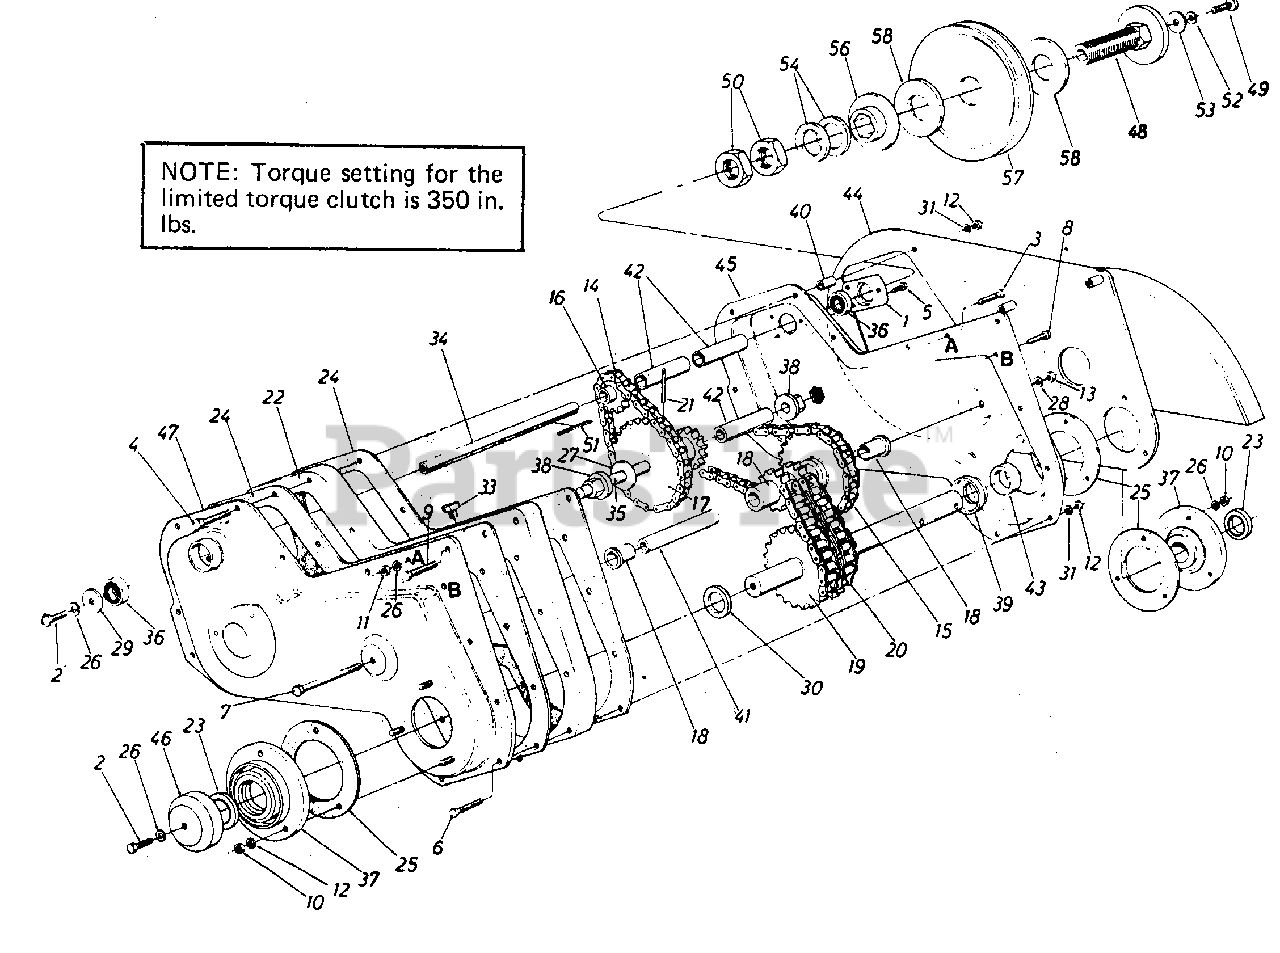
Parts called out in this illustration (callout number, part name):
1	Bearing Housing 1-3/8" Dia.
2	Hex Bolt 5/16-18 x .88" Lg. Spec.
3	Hex Bolt 5/16-18 x 1.50" Lg.*
4	Hex Bolt 1/4-20 x 2.75" Lg.*
5	Hex Wash. S-Tap. Scr. 1/4-20 x 50" Lg.
6	Hex Bolt 1/4-20 x 1.50" Lg.*
7	Hex Bolt 3/8-16 x 4.5" Lg.
8	Hex Wash. Hd. Bolt 1/4-20 x 1.5" Lg.
9	Hex Wash. TT Tap Scr. 5/16 18 x 1.75" Lg.
10	Hex Cent. L. Nut 5/16-18 Thd.
11	Hex Nut 5/16-18 Thd.*
12	Hex Nut 1/4-20 Thd.*
13	Hex Nut 3/8-16 Thd.*
14	#41 Chain 1/2" Pitch x 34 Links Endless
15	#42 Chain 1/2" Pitch x 48 Links-Endless
16	Sprocket 10Tooth.500" Pitch
17	10 & 28 Teeth Sprocket Ass'y.
18	8-2 & 28 Sprocket Sleeve Ass'y.
19	18-2 Sprocket Shaft Ass'y.
20	#50-2 Chain 5/8" Pitch x 28 Links-Endless
21	Spring Pin Spir. 1/4" Dia. x 1.50" Lg.
22	Spacer Block-Tiller Housing
23	Oil Seal Double Lip-l 1/4" Dia.
24	Gasket for Tiller Housing
25	Gasket for Brg.-Housing
26	L.-Wash. 5/16" I.D.*
27	Fl.-Wash. .640" I.D. x 1.24" O.D.
28	L.-Wash. 3/8" I.D. Heavy Duty
29	Fl.-Wash. .344" I.D. x.1.125"
30	Special Washer
31	L.-Wash. 1/4" I.D.
34	Jack Shaft .525" I.D. x 7.78" Lg.
35	Sprocket Shaft .63" Dia. x 5.0" Lg.
36	Ball Brg. .62" I.D. x 1.38" O.D.
37	Bearing Housing-1 1/4"
38	Hex Flange Brg.
39	Spacer 1.25" I.D. x 2.0" O.D.
40	Spacer .28" I.D. x .62" O.D. x .90" Lg.
41	Spacer.38" I.D. x .62" O.D. x 3.44" Lg.
42	Spacer.62" I.D. x .88" O.D. x 1.56" Lg.
43	Spacer 1.25" I.D. x 1.62" O.D. x . 50" Lg.
46	Dust Cap .320" Dia. Hole
49	Hex Bolt 5/16-18 x 1.25" Lg. Grade 5
50	Hex Jam Nut 1.0-14 x 28 Thd.
51	Sq. Key 3/16 x 1.50" Lg.
52	L.-Wash. 5/16" I.D.*
53	Fl.-Wash. .344" I.D. x 1.125" O.D.
54	Spring Bell Wash. 1.0" I.D. x 2.0" O.D.
56	Floating Disc 3-1/4" O.D. x 1.0" I.D.
57	5/8 V-Pulley 1.50" I.D. x 6.50"
58	Friction Pad 3-1/4" O.D. x 3/8" I.D.
